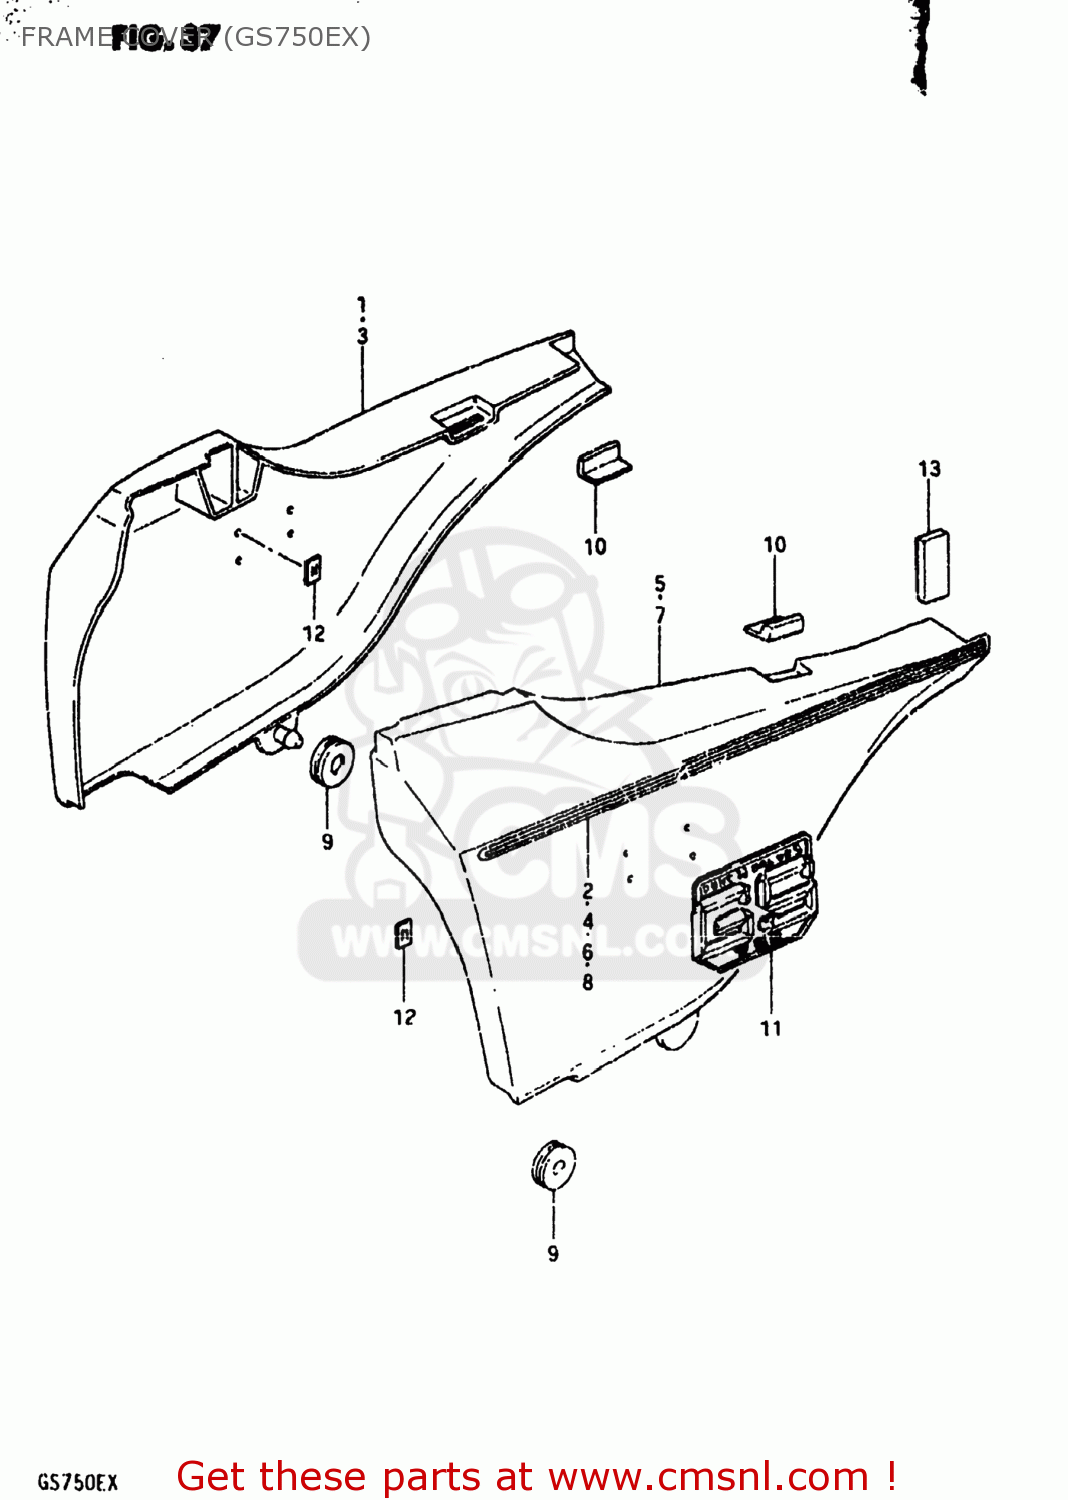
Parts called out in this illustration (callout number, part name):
1	COVER,FRAME,RIGHT
2	TAPE,FRAME COVER
3	COVER,FRAME,RIGHT
4	TAPE,FRAME COVER
5	COVER,FRAME,LEFT
6	TAPE,FRAME COVER,LEFT
7	COVER,FRAME,LEFT
8	TAPE,FRAME COVER,LEFT
9	CUSHION
10	CUSHION,FRAME COVER
11	EMBLEM,FRAME COVER
12	NUT
13	RUBBER,FRAME COVER
